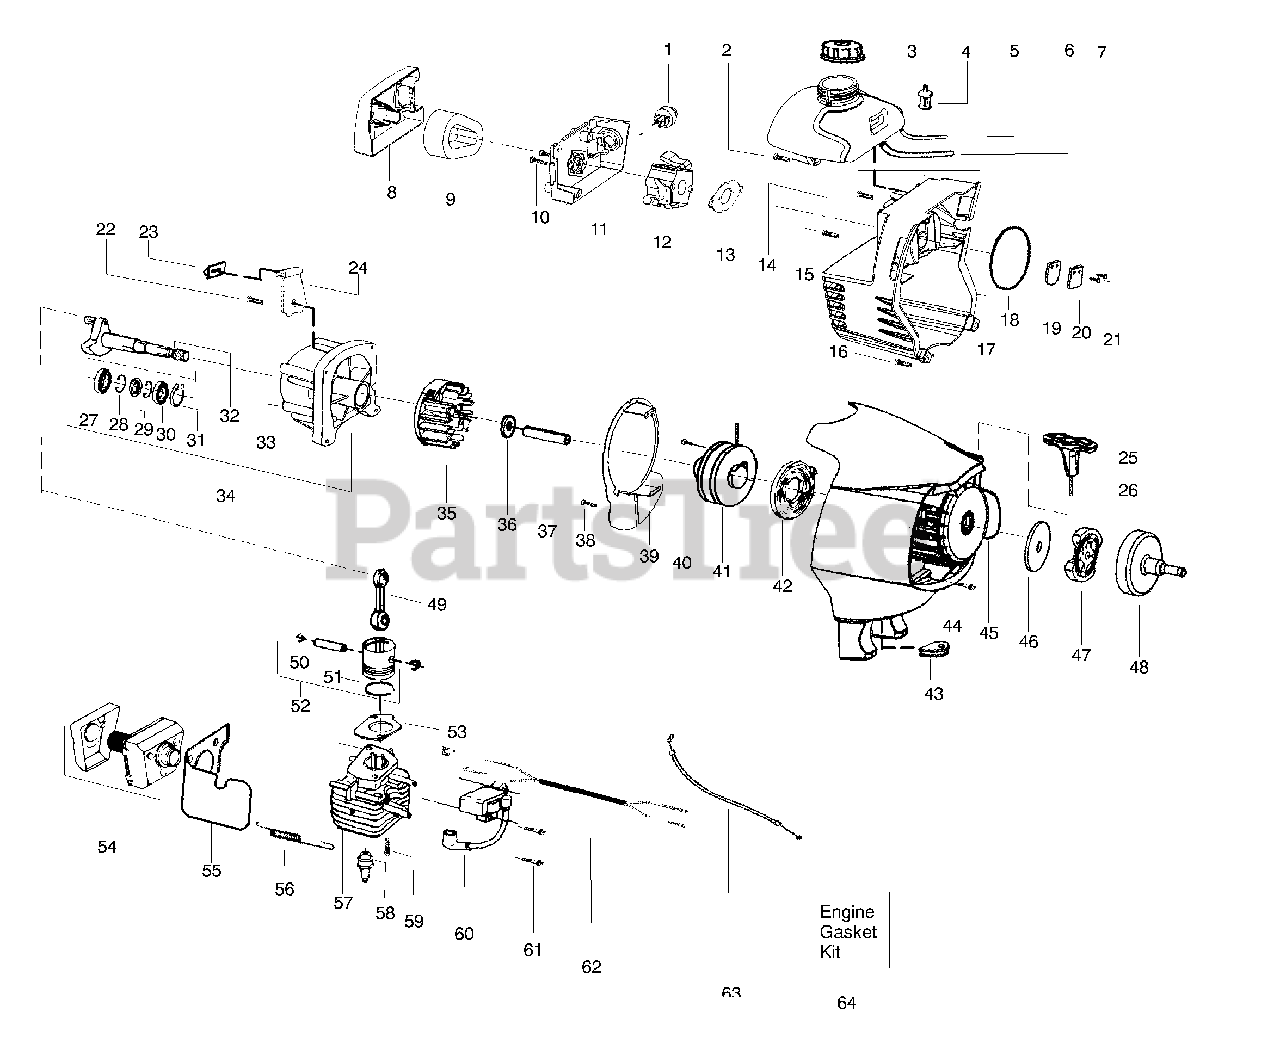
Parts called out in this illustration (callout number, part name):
1	Bulb-purge
2	Screw-tank
3	Assy-Fuel cap w/ret.
4	Assy-Fuel pick-up
5	Kit-Fuel line
6	Kit-Fuel/Purge line
8	Cover-Air box
9	Filter-Air
10	Screw-carb.
12	Kit-Carb Assy. (Wt-619)
12	Kit-Carb Assy. (WT-628)
13	Gasket-Carb. (kit)
14	Assy-Fuel tank
15	Screw-crankcase
16	Screw-shrd to f/hsg.
18	O-ring-c/case (kit)
19	Valve-reed
20	Stop-reed valve
21	Screw-reed valve
22	Screw-tank retainer
23	Isolator-fuel tank
24	Ret.-fuel tank
25	Handle-starter
26	Kit-Rope
27	Bearing-inner
28	Retainer
30	Bearing-outer
31	Retainer-crankshaft
32	Assy-crankshaft
33	Assy-crankcase
34	Kit-Assy-c'case/c'shaft
35	Kit-Flywheel Assy.
38	Screw-baffle
39	Plate-baffle
40	Screw-rope
41	Kit-pulley
42	Spring-starter
44	Screw-F/hsg
45	Housing-Fan w/eyelet
46	Washer-Clutch
47	Assy.-Clutch
48	Assy-Drum
49	Assy-Connecting rod
50	Retainer-piston pin
51	Ring-Piston
52	Kit-Piston
53	Gasket-Cylinder (kit)
54	Kit-Muffler
55	Heat shield/air dam
56	Spring-muffler
57	Kit-Cylinder
58	Spark plug (RCJ-6Y)
59	Bolt-Cylinder
60	Module-Ignition
61	Screw-module
62	Assy-Leadwire
63	Assy-Throttle Cable
64	Kit-Gasket
